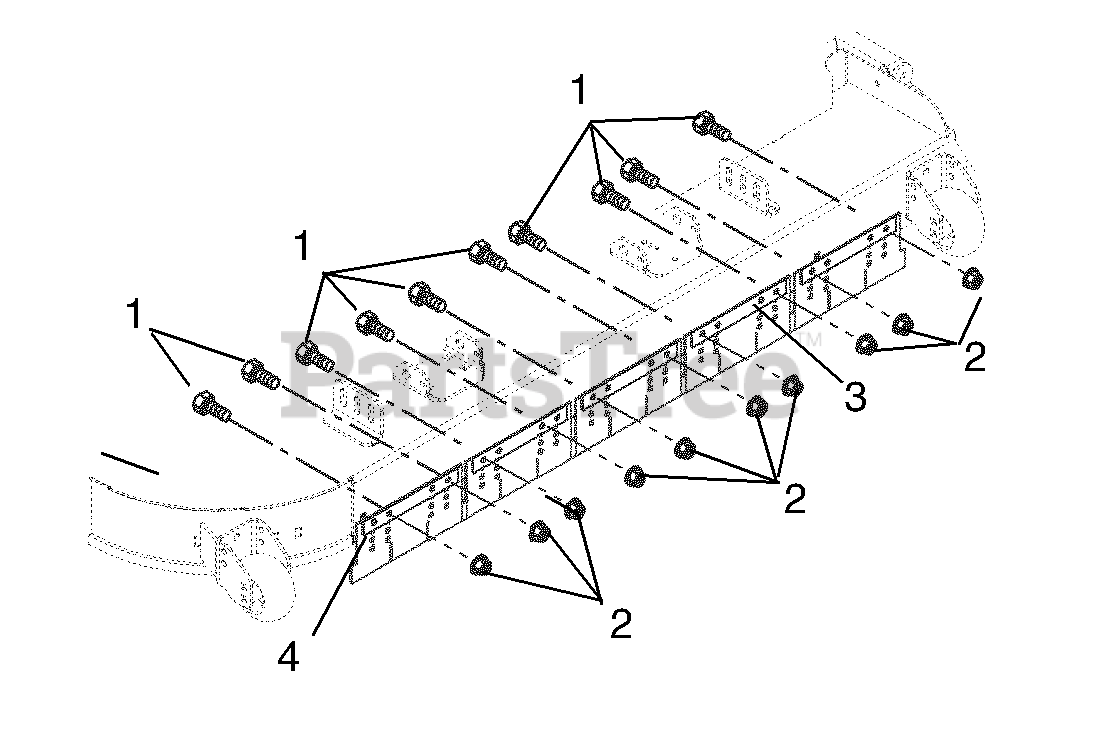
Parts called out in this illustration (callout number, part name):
1	@BLT-HEX .38-16X1.00 GR5 YWZC
2	@NUT-LK-TOP-FLG .38-16 YWZC
3	SKIRT, RUBBER STRIPER
4	BAR, STRIPER
